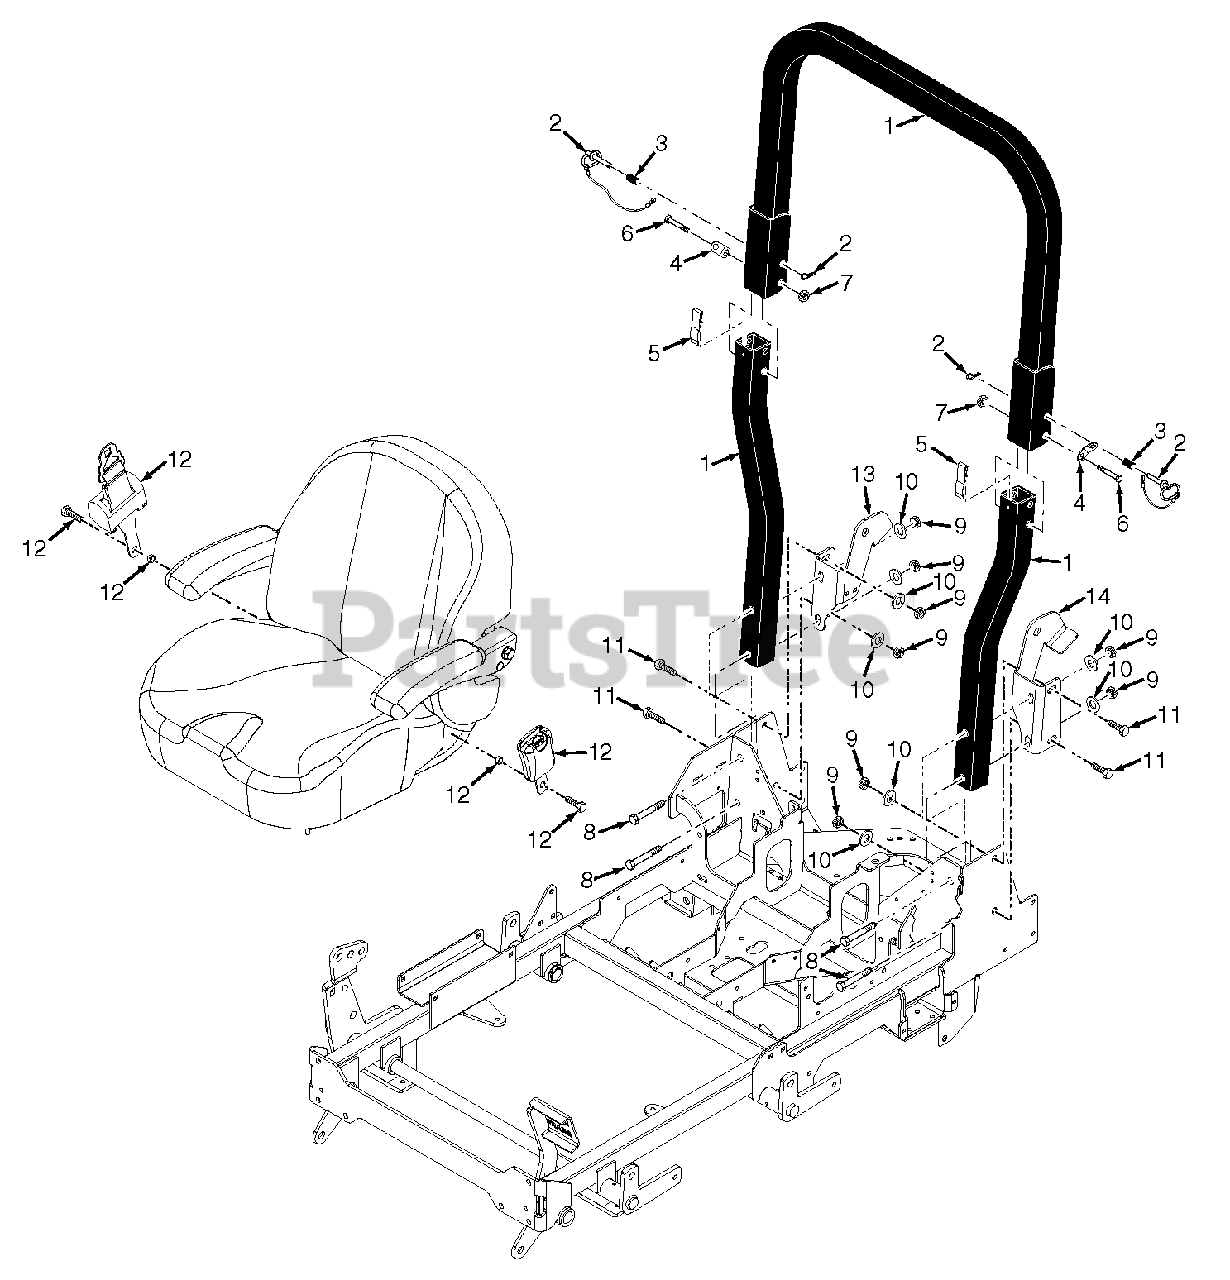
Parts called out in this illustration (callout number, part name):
1	ROPS Assembly, Foldable
2	Pin Assembly
3	Spring, ROPS
4	Clip, ROPS
5	Spring, ROPS Anti-Rattle
6	Bolt, Hex Head 1/2-13 x 3-1/4"
7	Nut, Elastic Stop 1/2-13
8	Bolt, Hex Head 1/2-13 x 3-1/2"
9	Nut, Center Lock 1/2-13
10	Flatwasher, 1/2-.562 x 1.375 x .109
11	Bolt, Hex Head 1/2-13 x 1-1/4"
12	Seat Belt Kit
13	ROPS Mount, RH
14	ROPS Mount, LH
